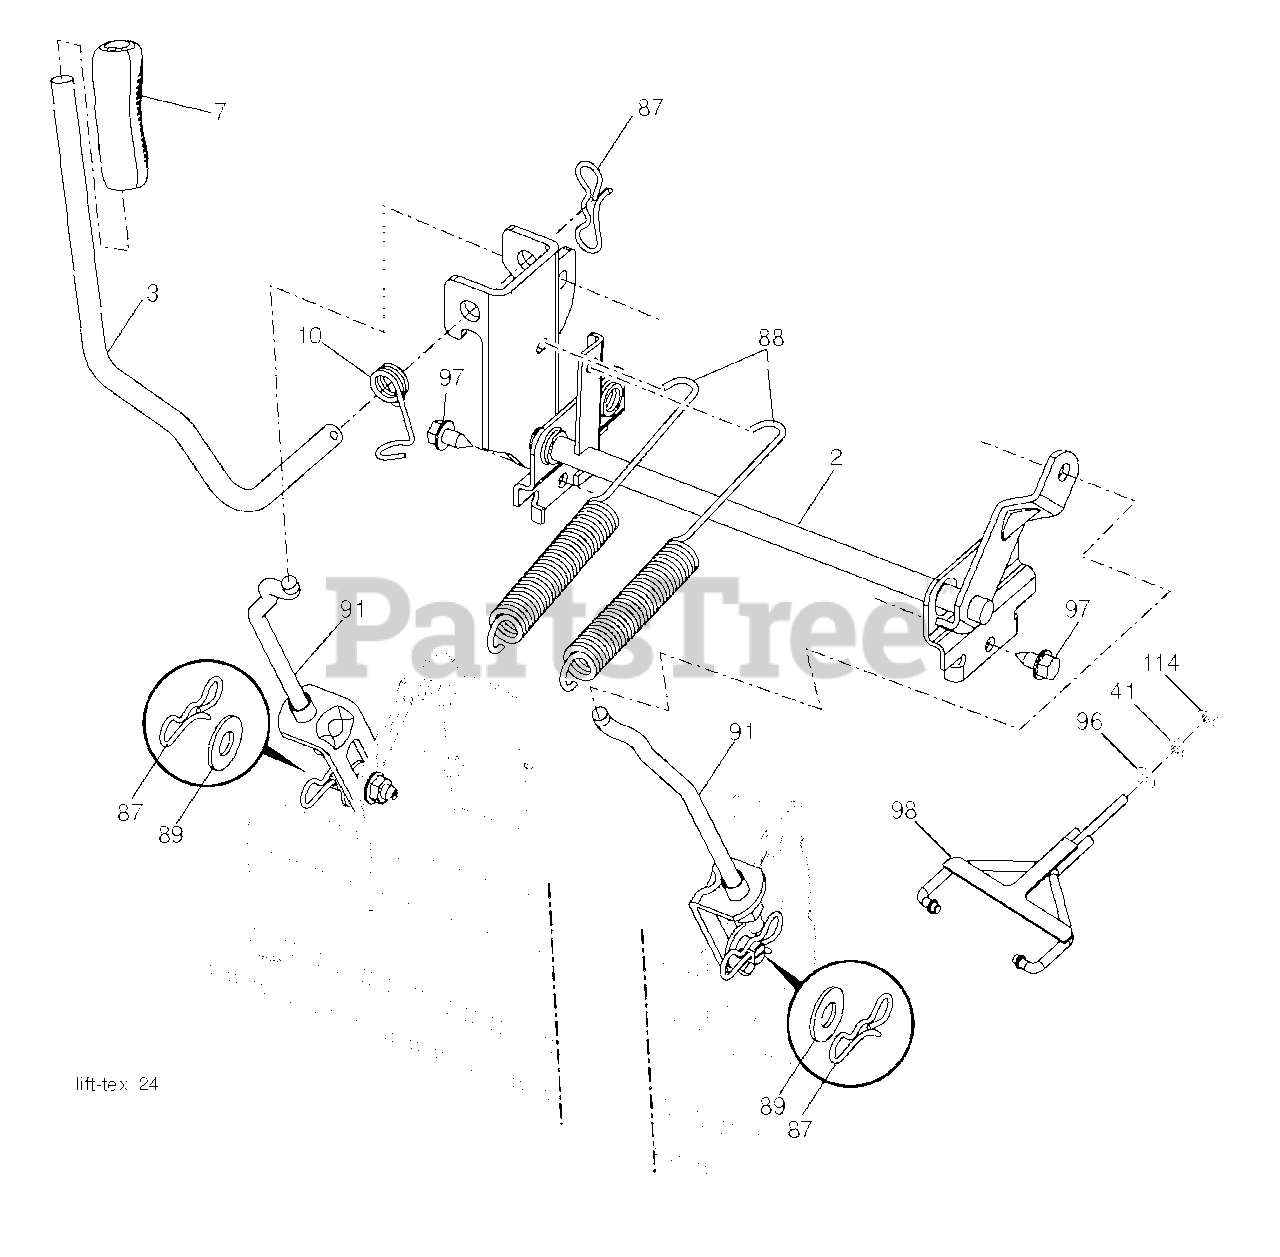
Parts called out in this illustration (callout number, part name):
2	SHAFT.ASM.CROSS.LIFT
3	LEVER.LIFT.HANDLE.GT
7	GRIP.HANDLE.LIFT.PVC.BLACK
10	SPRING.TORSION.LIFT.HANDLE
41	NUT, LIFT LINK 7/16-20
87	PIN.COTTER.7/16.BOW TI.
88	SPRING.LIFT.ASSIST
89	WASHER.CLEAR.ZINC
91	LINK.ASM.LIFT.54"TG
96	BUSHING SPHERICAL SUSP. FRONT
97	SCREW, 3/8-16X3/4
98	SUSPENSION WLDT FRONT DECK
114	NUT **
